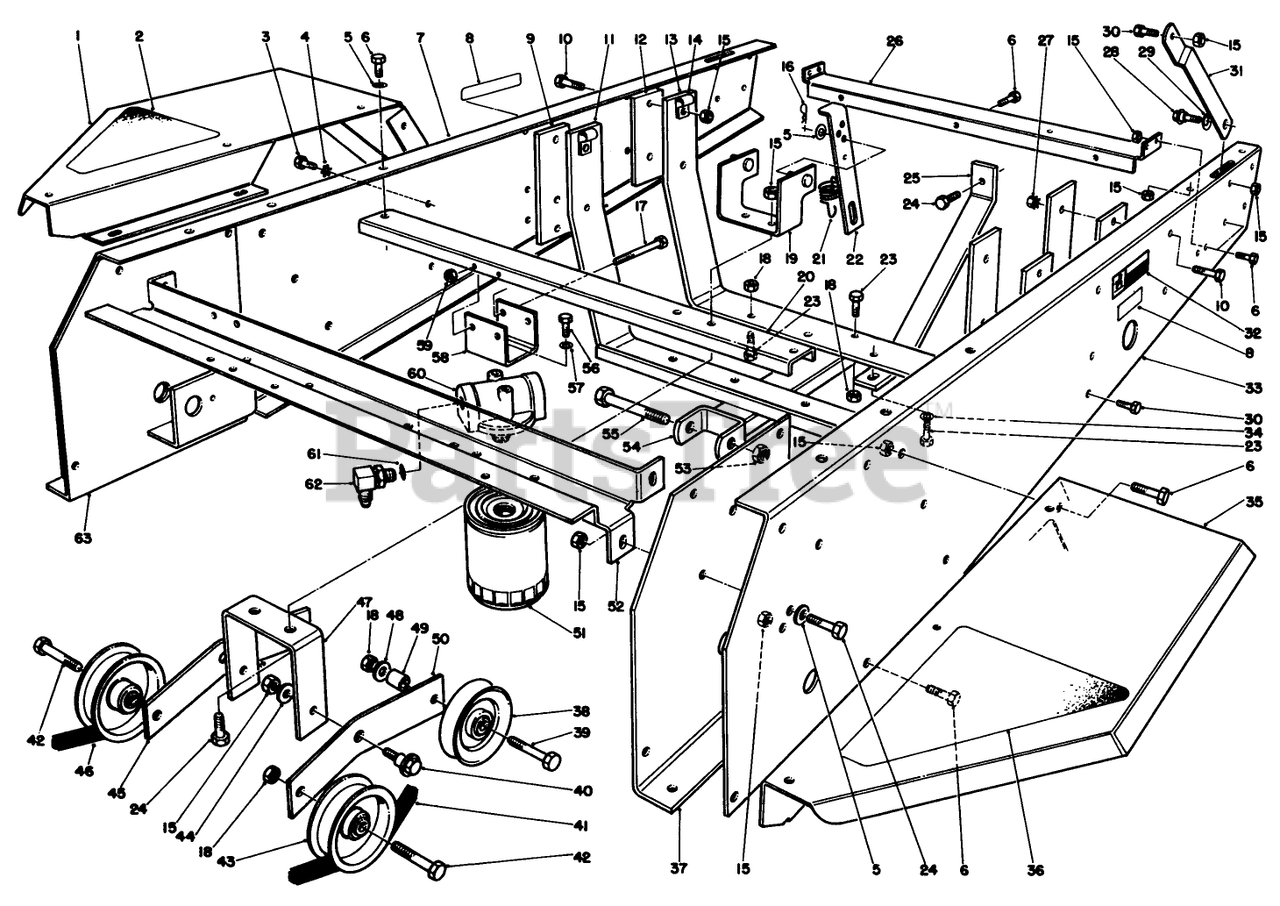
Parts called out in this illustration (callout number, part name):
3	SCREW-HH
4	WASHER-LOCK
5	WASHER-PLAIN
6	SCREW-HH
8	DECAL-ROTATING
9	FRONT ENG PLATE
10	SCREW-HH
11	ENGINE MT WA *B
12	REAR ENG PLATE
14	CLAMP-R
15	NUT-LOCK, NI
16	PIN-COTTER
17	SCREW-HH
18	NUT-LOCK, NI
20	MIDDLE CHANNEL WA *B
21	IDLER SPRING
23	SCREW-HH
24	SCREW-HH
27	NUT-KEPS
28	SCREW-SHOULDER
29	WASHER-SPRING
30	SCREW-HH
32	DECAL-HOT
34	SCREW-HH
39	SCREW-HH
40	SCREW-SHOULDER
41	V-BELT, JACKSHAFT
42	SCREW-HH
43	Flat Idler
44	WASHER
46	V-BELT, TRACTION
48	WASHER-FLAT
49	SPACER-WEIGHT
51	FILTER-OIL, TRANSMISSION
53	NUT-HEX
56	SCREW-HH
57	SCREW-HH
58	BRACKET - FILTER HEAD
59	NUT-LOCK, NI
60	FILTER HD ASM
61	O-RING
